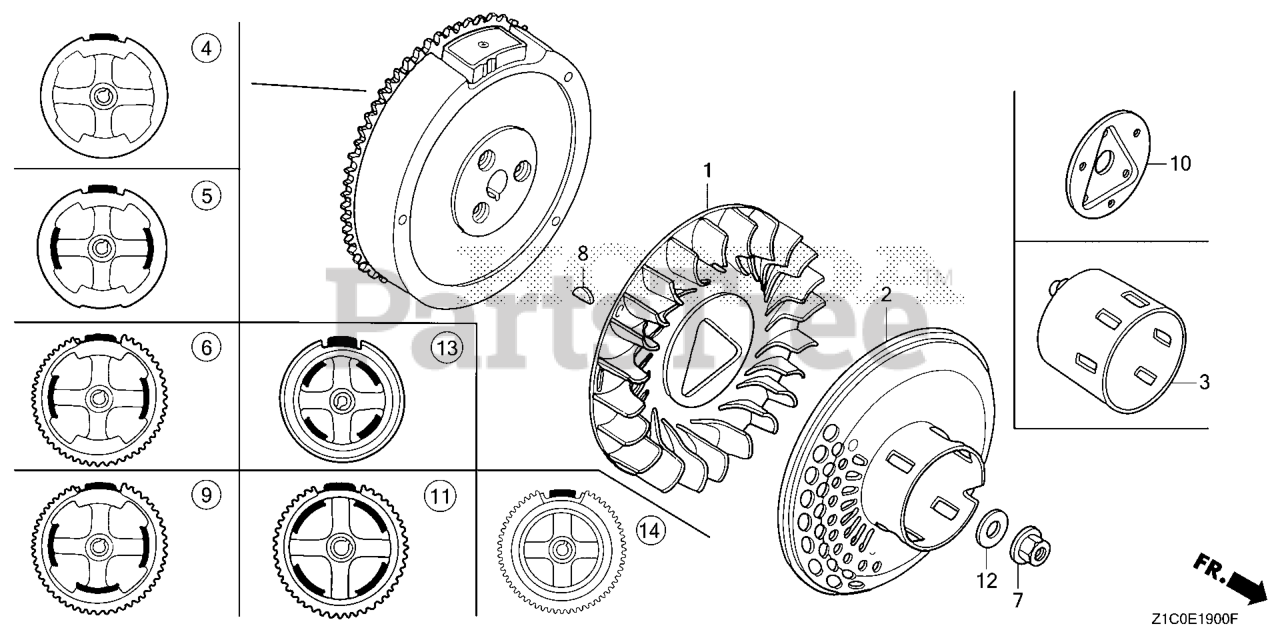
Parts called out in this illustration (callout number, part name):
1	FAN, COOLING
3	PULLEY, STARTER
7	NUT, SPECIAL (16MM) (1)
8	KEY, SPECIAL WOODRUFF (25X18)
